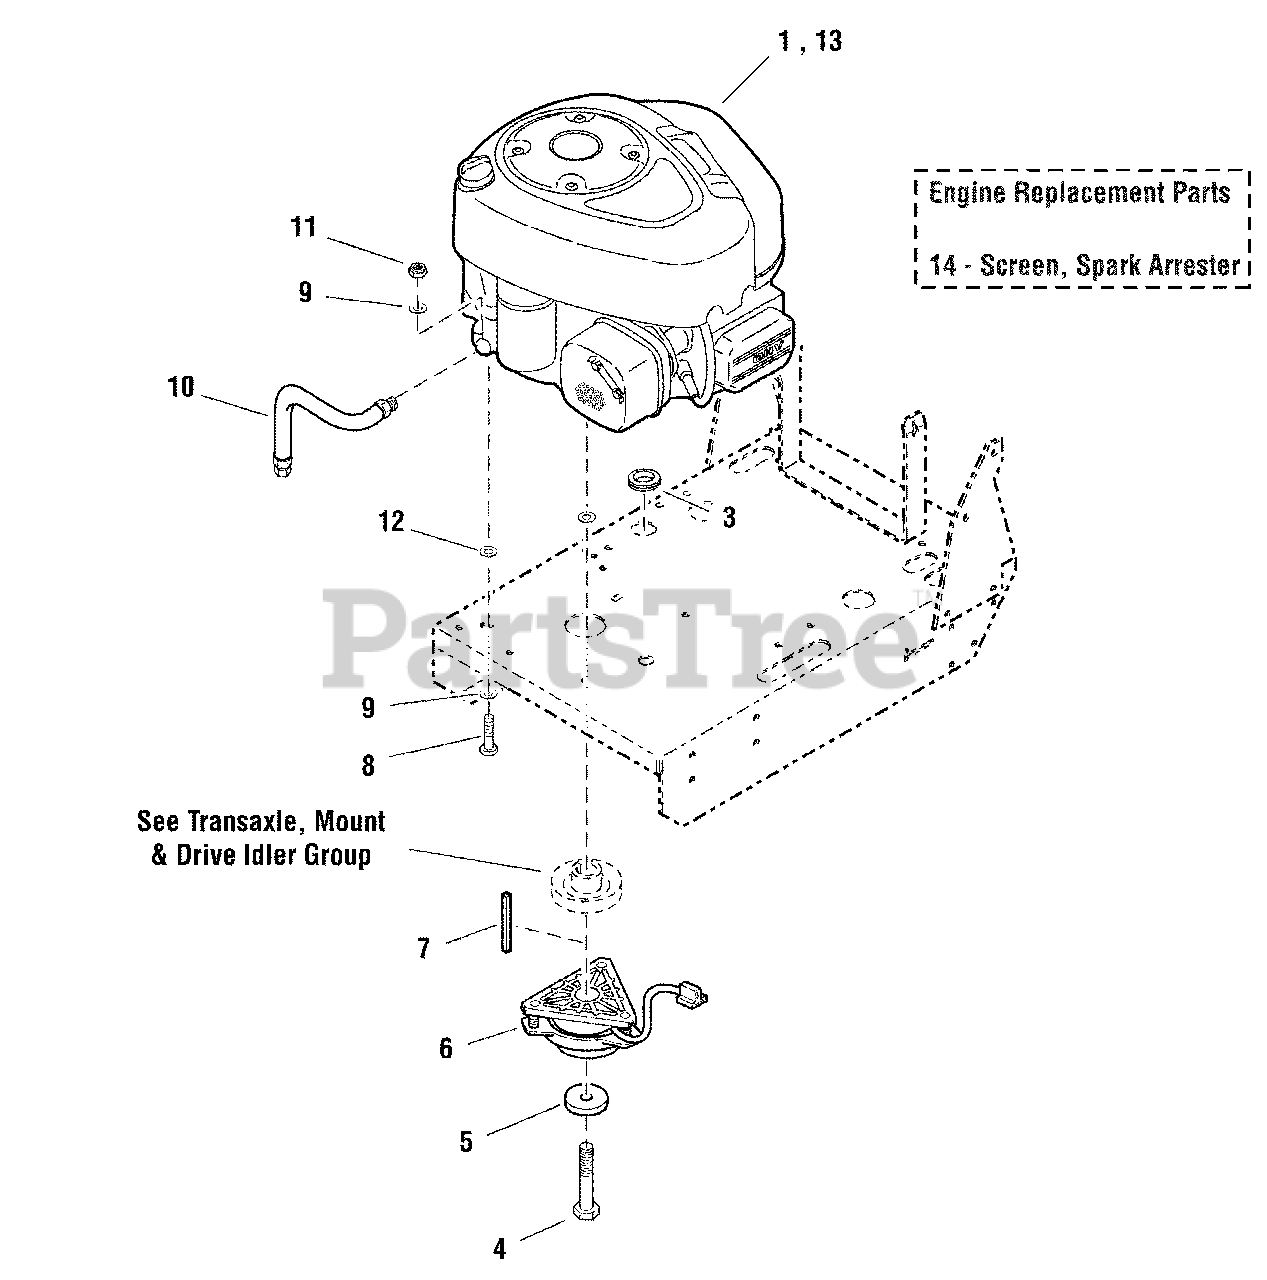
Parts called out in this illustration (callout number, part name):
1	* ENGINE, Briggs & Stratton, INTEK
4	CRANKSHAFT BOLT, 7/16 x 2-3/4
5	CLUTCH RETAINER
6	ELECTRIC CLUTCH
7	KEY, 1/4 Sq. x 2
8	CAPSCREW, Hex Head, 5/16-18 x 2-1/2
9	WASHER, 5/16
10	OIL DRAIN HOSE
11	NUT, Hex Nylon Lock, 5/16-18
12	WASHER, 5/16" Internal Tooth Lock
13	* ENGINE, Briggs & Stratton, ELS
